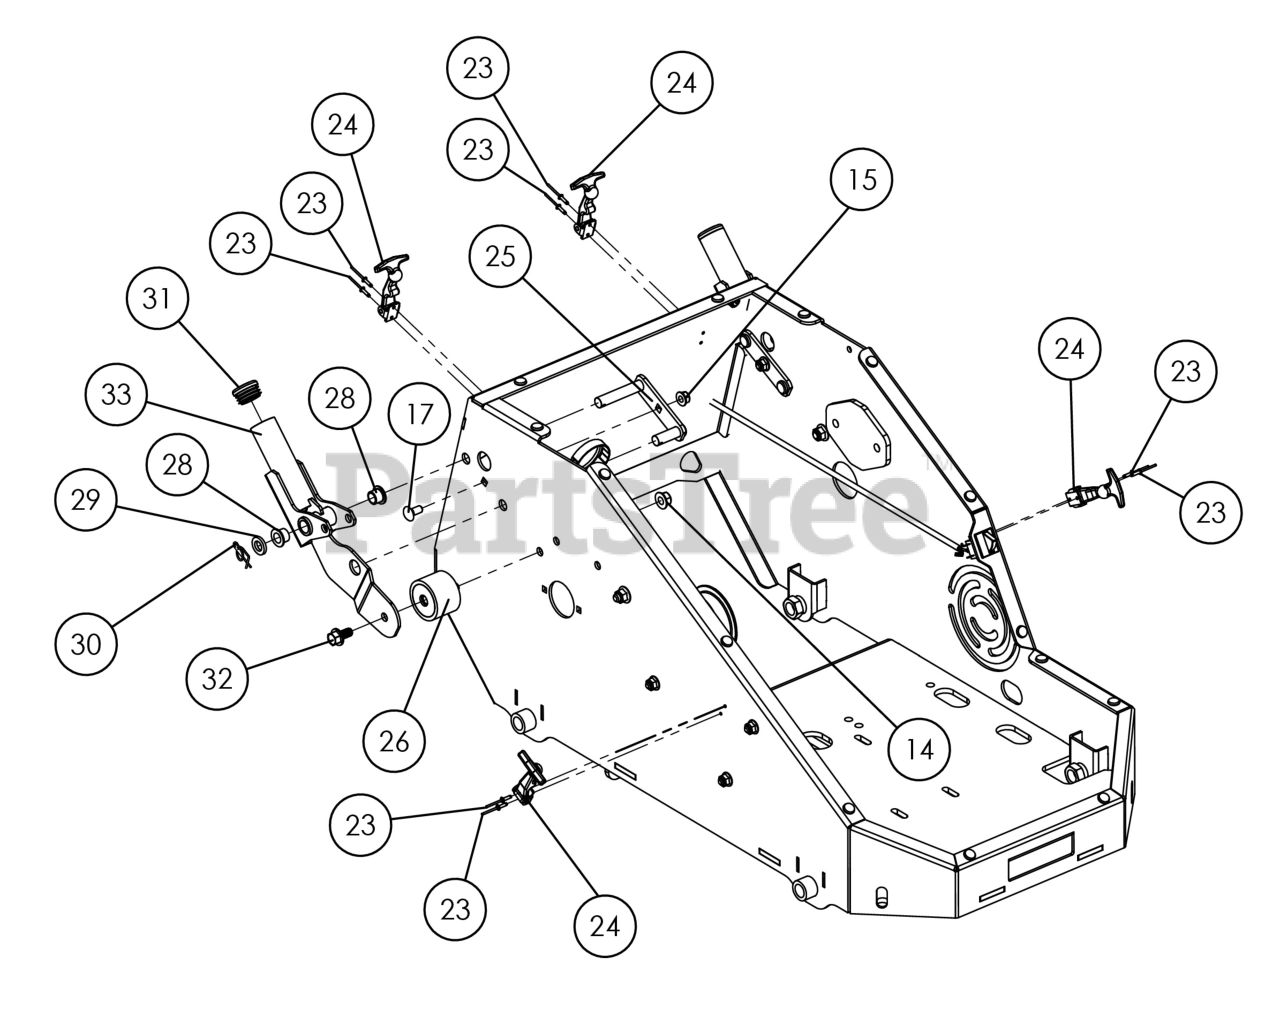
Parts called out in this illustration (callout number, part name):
14	NUT-HEX-NYLK, FLG .375"-16 ZP
15	NUT-HEX-NYLK, FLG .3125-18 ZP
17	BOLT CARRIAGE 5/16"-18 X 3/4" ZP
23	STAINLESS RIVET, 1/8 DIA X 1/4
24	SEE: LATCH DRAW RUBBER 381003-01 & LATCH CLEAT 381003-02
25	WA, ISO MOUNT
26	ISOLATOR, VIBRATION HANDLE SC181H
28	BUSHING .500" ID
29	WSHR-STL,FLT .500"X.875"X.134" MAB ZP
30	RING, RUE .500"
31	PLUG TUBE INSERT 1.25" O.D.
32	SER HEX WASHER 3/8" - 16
33	WA, REVOLVER RH
